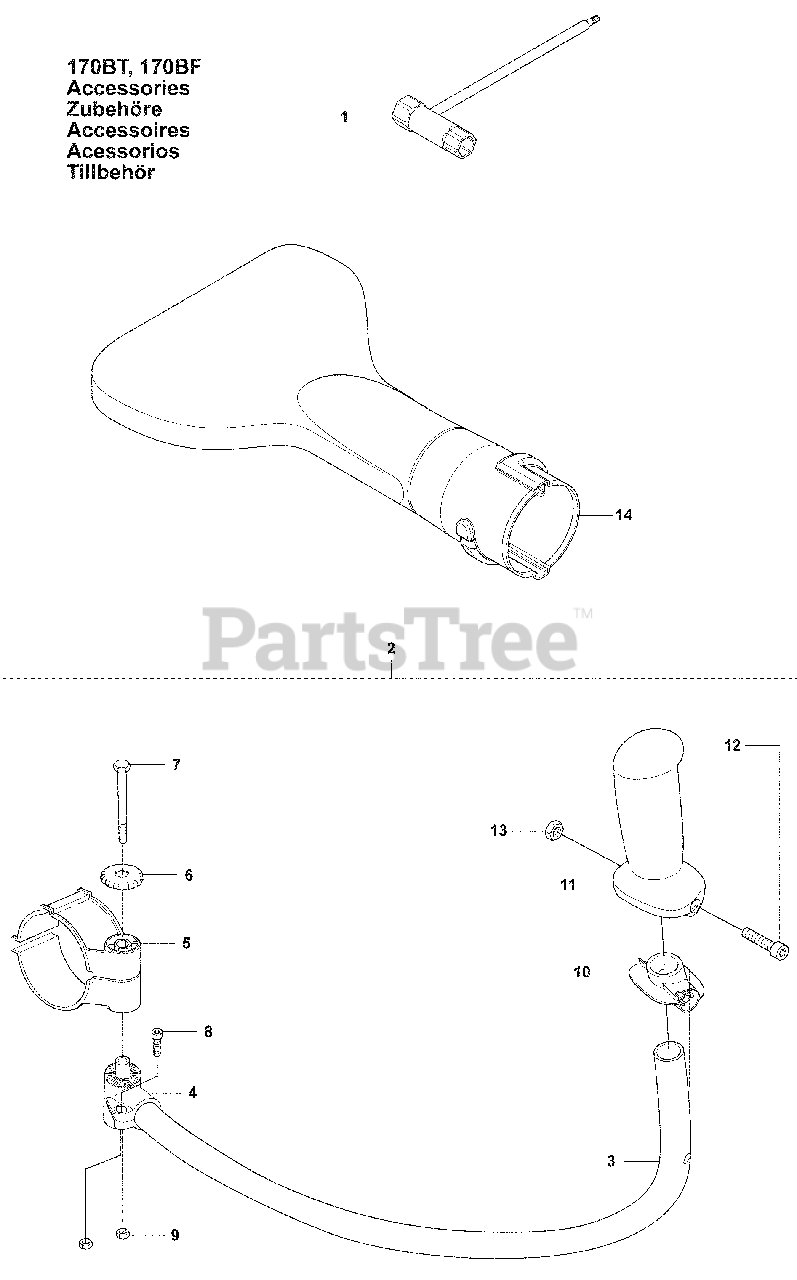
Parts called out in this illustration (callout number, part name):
1	SOCKET
2	Handle, 170 BT
5	HOLDER TH
6	Air Filter Cover Knob
8	Screw, MC6S 5 X 10
9	Hex Nut, M5 X .80 DIN
13	Hex Nut, M5 X .80 DIN
14	Flat Nozzle
